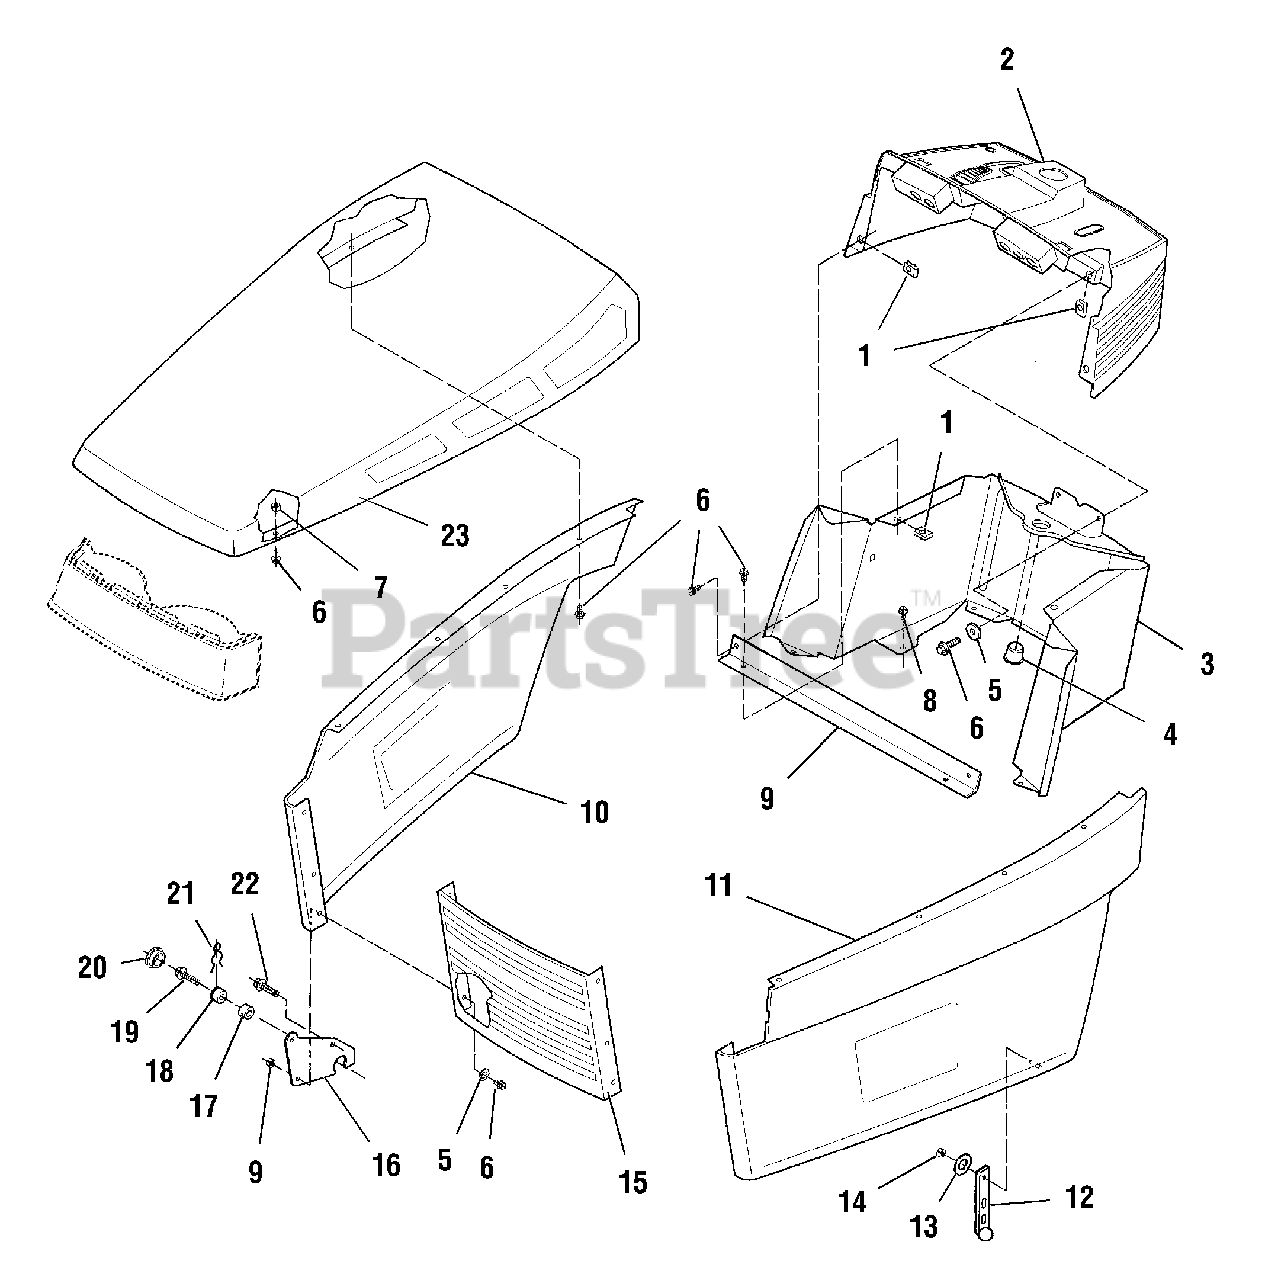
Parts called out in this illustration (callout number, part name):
1	PAL NUT, 1/4-20
2	DASHBOARD, LENSES & BEZELS ASSY.
3	DASH, Lower
4	BUSHING, Nylon
5	WASHER, Plain, 1/4
6	CAPSCREW, Whizlock, 1/4-20 x 5/8
7	NUT, Hex, Full Lock, 1/4-20
8	SCREW, Taptite, 1/4-20 x 1/2
9	SUPPORT, Upper Dash
10	SIDE PANEL ASSY., RH, Orange
10	SIDE PANEL ASSY., RH, Red
11	SIDE PANEL ASSY., LH, Orange
11	SIDE PANEL ASSY., LH, Red
12	STRAP, Hood
13	WASHER, Special
14	NUT, Hex, Lock, Nylon #10-24
16	HINGE, Hood
18	PIVOT, Hood
19	SCREW, Taptite, 5/16-18 x 1
20	SPACER, Hood
21	CLIP, Hairpin
22	SCREW, Taptite, 5/16-18 x 5/8
23	HOOD, Orange
